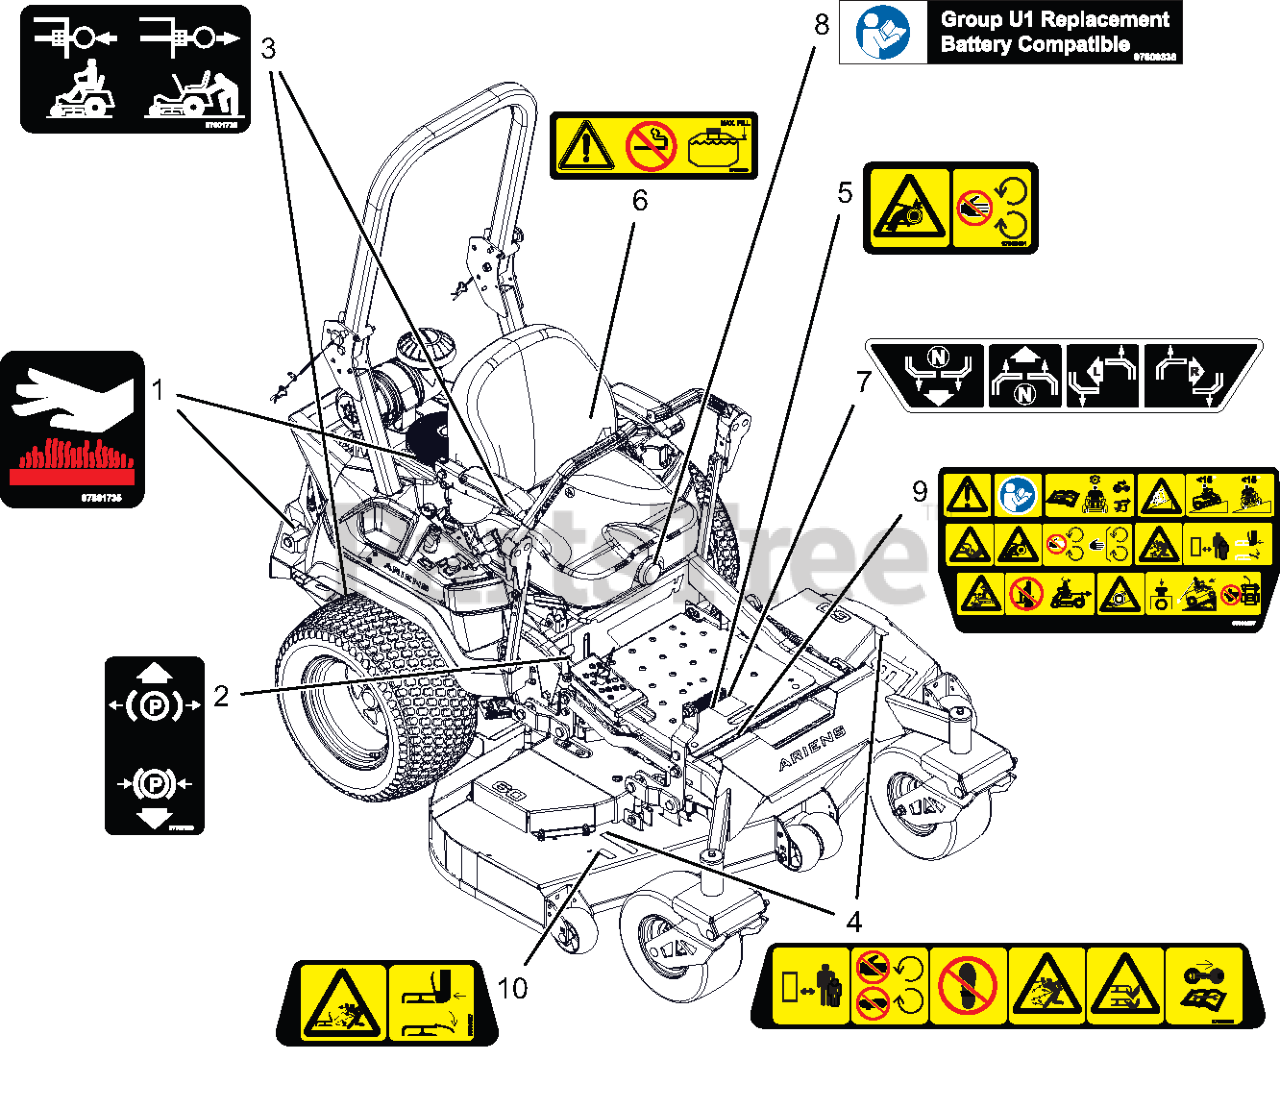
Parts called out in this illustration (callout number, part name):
1	DECAL- HOT SURFACE
2	DECAL, PARKING BRAKE LEVER
3	DECAL- TRANSAXLE DISCONNECT
4	DECAL- SAFETY - MOWER DECK
5	DECAL, SAFETY - GUARDING
6	DECAL, FUEL WARNING
7	DECAL, INSTRUCTION - STEERING
8	DECAL, U1 BATTERY REPLACEMENT
9	DECAL, MAIN SAFETY
10	DECAL- SAFETY - DECK GUARDING
